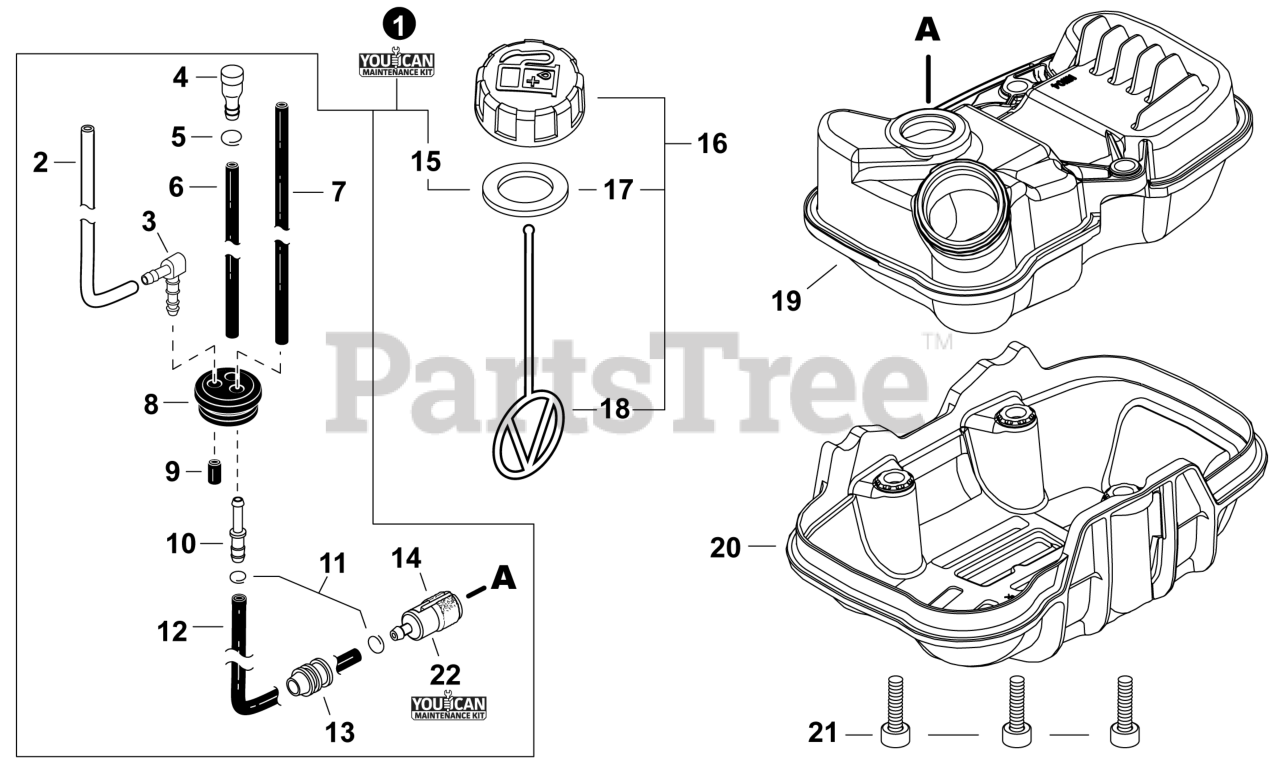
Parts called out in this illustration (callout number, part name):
1	FUEL SYSTEM KIT - YOUCANT
2	PIPE, FUEL 3x6x75 CLEAR
3	CONNECTOR, PIPE
4	VENT ASSY
5	CLIP 6.5 MM
6	PIPE, FUEL 3x6x85 BLACK
7	PIPE, FUEL 3x5.5x80 BLACK
8	GROMMET, FUEL
9	PIPE, FUEL 3x7x10 BLACK
10	CONNECTOR, PIPE 5x3.5
12	PIPE, FUEL 3x5x115 BLACK
14	FILTER, FUEL
15	GASKET, FUEL CAP
16	CAP ASSY, FUEL
17	GASKET, FUEL CAP
18	CONNECTOR, CAP L= 123
19	TANK, FUEL
20	GUARD, FUEL TANK
21	BOLT 5x20
22	TUNE-UP KIT - YOUCANT
